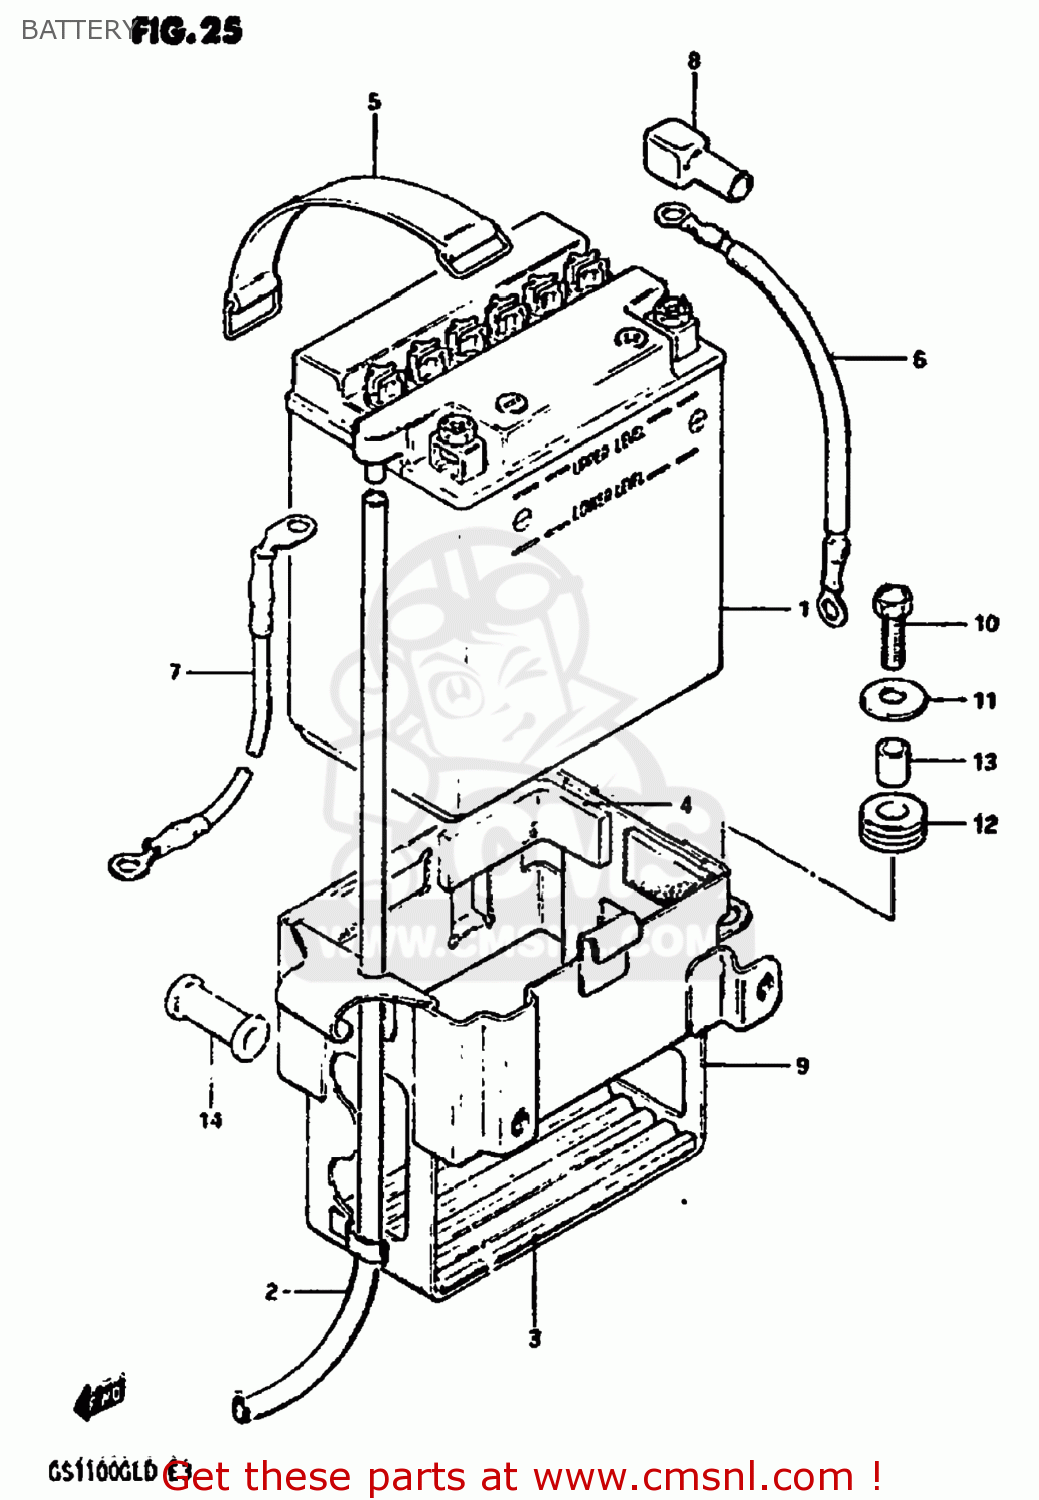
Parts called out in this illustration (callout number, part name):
1	BATTERY ASSY (12V)
2	HOSE,BATTERY EXHAUST
3	PROTECTOR,BATTERY
4	PROTECTOR(20X90)X4
5	BAND
6	WIRE,BATTERY PLUS
7	LEAD WIRE,BATTERY(-)
8	CAP,TERMINAL
9	HOLDER,BATTERY
10	BOLT, UPPER
11	WASHER(6,5X22X1.6)
12	CUSHION
13	SPACER(6.2X8.3X5.7)
14	CUSHION
